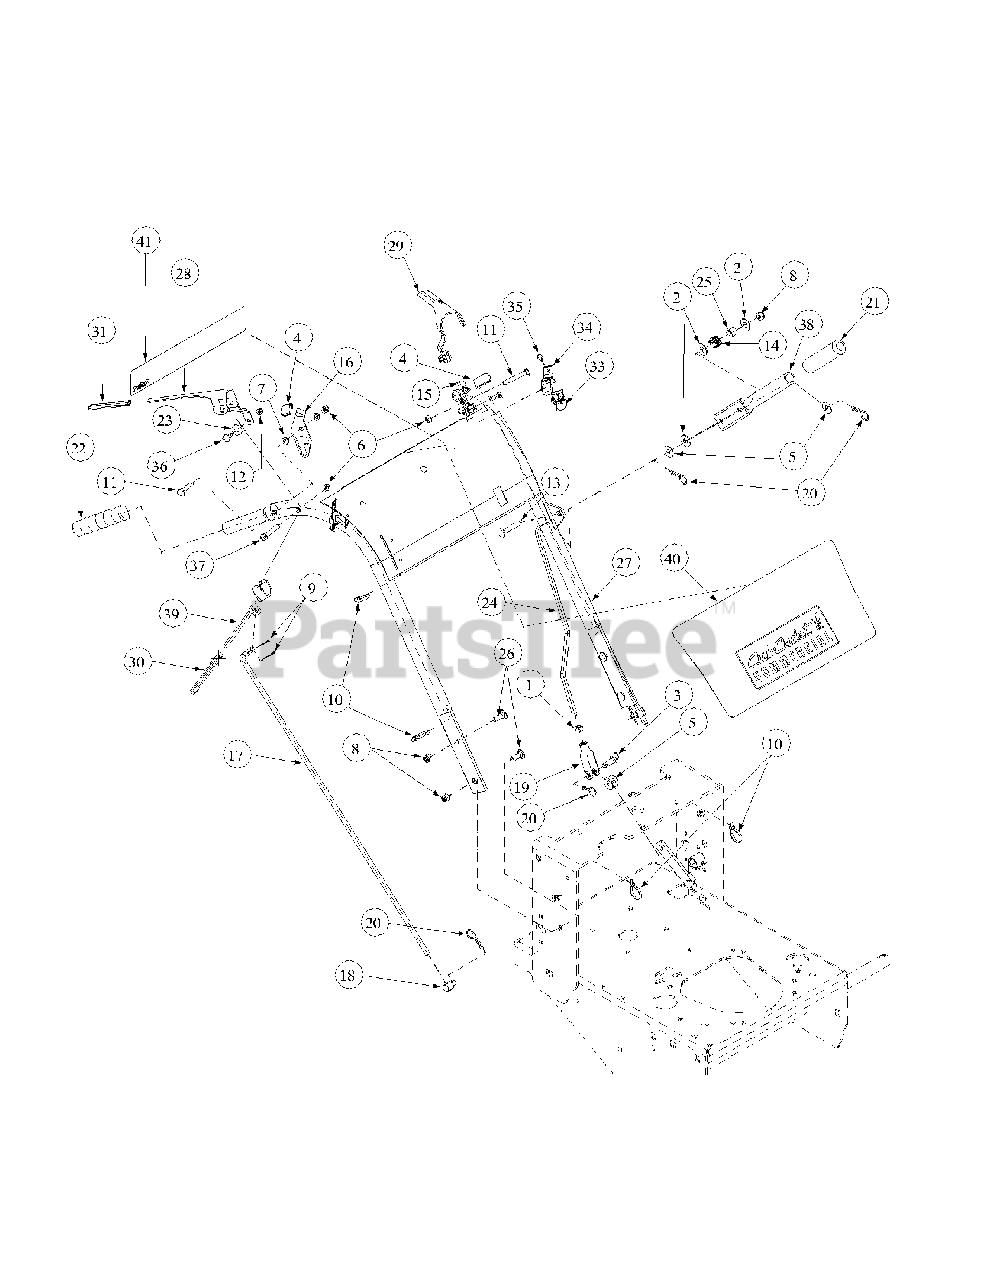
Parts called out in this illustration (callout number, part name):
1	Hex Nut, 3/8-16
2	Flat Washer, 3/8 Zinc
3	Clevis Pin, 3/8 x 1-1/8 Zinc
4	Grip, Neutral Latch, 1.25"
5	Flat Washer, 3/8 Zinc
6	Nylock Nut, 5/16-18
7	Flat Washer, 5/16 Zinc
8	Lock Nut, Nylon Insert, 3/8-16
9	Cotter Pin, 3/32 x 3/4, Zinc
10	Cable Tie, 3/16 x .05 x 7.4
11	Hex Cap Screw, 5/16-18 x 2
12	Lock Nut, Nylon Insert
13	Carriage Bolt, 3/8-16 x 2
14	Spring, .850 OD x 1
15	Neutral Latch, Left Hand
16	Neutral Latch, Right Hand
17	Steering Control Rod
18	Joint Swivel
19	Yoke, 3/8-16 Female
20	Hair Pin 3/8-1/2
21	Handle Grip, Black, 1"
22	Plastic Handle Grip, Black, 4-5/8
23	Control Rod, Hydro Spacer
24	Blade Clutch Rod
25	Spring Sleeve
26	Carriage Bolt, 3/8-16 x 2
27	Handle Assembly
28	Operator Presence Control RH
29	Operator Presence Control LH
30	Control Sleeve, Black
31	Operator Control Sleeve, Yellow
32	Harness Assembly Adapter
33	Switch Mounting Snap
34	Operator Presence Return Spring
35	Hex Index Washer Screw, 0.500
36	Shoulder Screw, .38 x .412, 1/4-28
37	Hex Cap Screw, 5/16-18, 2.00
38	Blade Clutch Lever
39	Lever Assembly Control
40	Label Commercial Mower Panel
41	Label Commercial Mower Instruction
